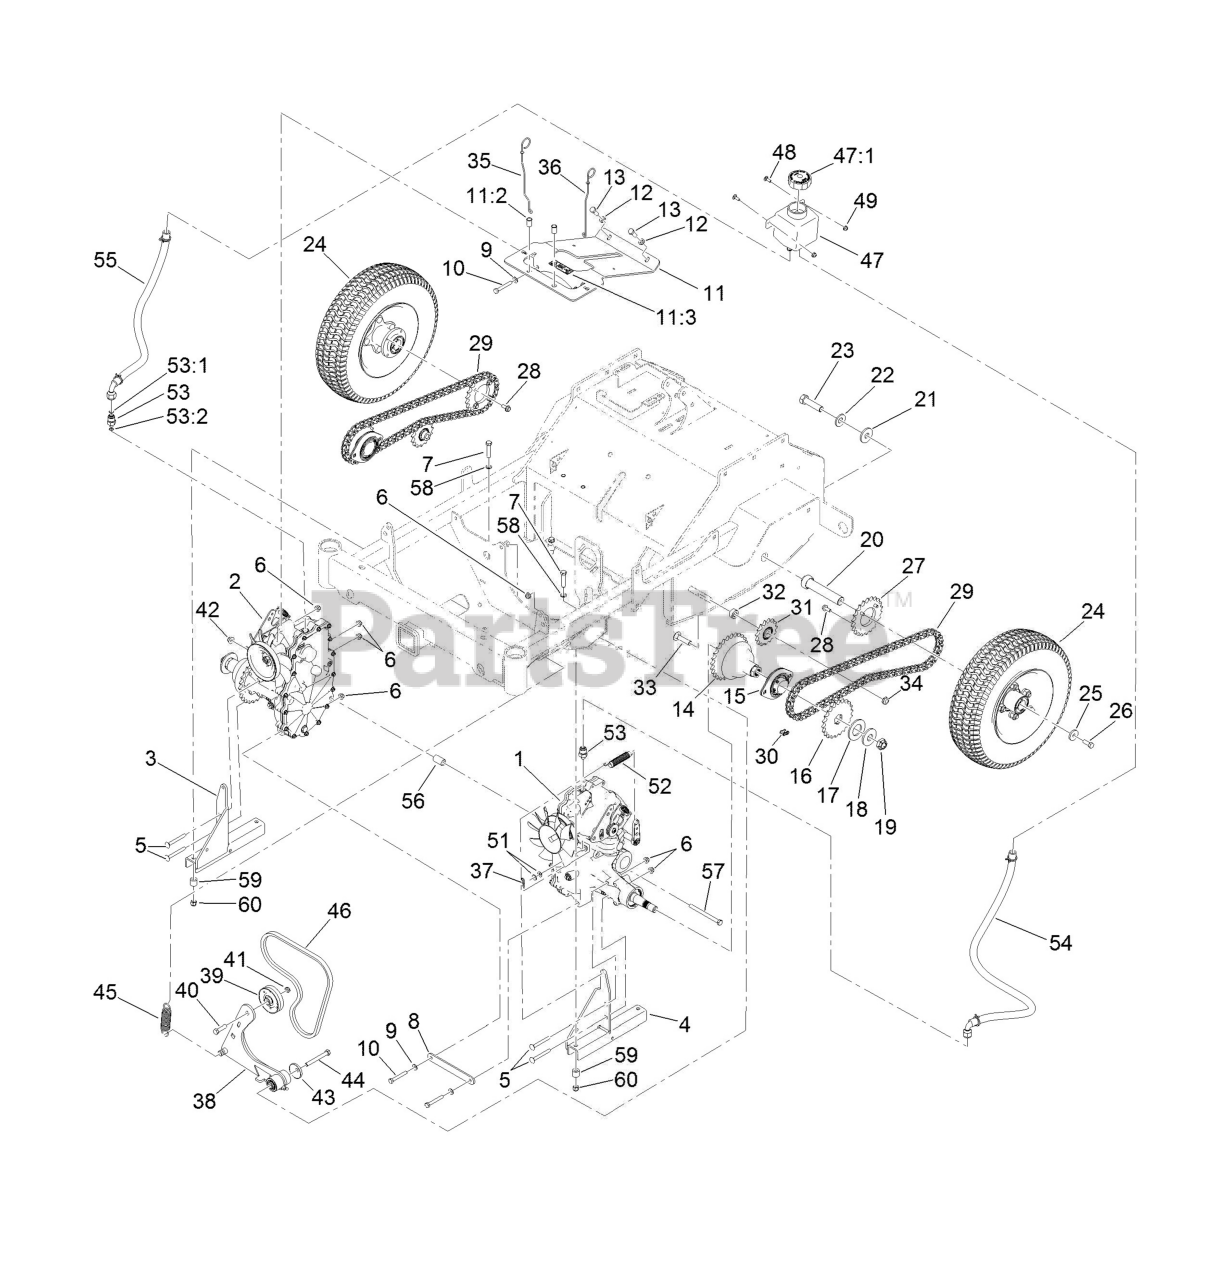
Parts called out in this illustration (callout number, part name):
1	HYDRO-ZT3100, LH
2	HYDRO-ZT3100, RH
3	MOUNT-HYDRO, RH
4	MOUNT-HYDRO, LH
5	SCREW-CARR
6	NUT-HF, NI
7	SCREW-HH
8	Crossmember-Transmission
9	WASHER-SPRING
10	SCREW-HH
11	SUPPORT-COVER
11:2	NUT-CLINCH
11:3	DECAL-DANGER
12	WASHER-LOCK
13	SCREW-HH
14	HUB-BELL
15	BEARING-FLANGED
16	SPROCKET
17	WASHER-SPACER
18	Washer-Belleville
19	NUT-LOCK
20	AXLE-WHEEL, DRIVE
21	WASHER-SPACER
22	Washer-Belleville
23	Screw-HH
24	WHEEL AND TIRE ASM 16X4.5-8, BLACK RIM
25	Washer-Flat
26	SCREW-HH, LOCK
27	SPROCKET
28	SCREW-HHF
29	CHAIN-ROLLER
30	LINK-CONNECTING
31	SPROCKET-IDLER, 15T
33	Screw-CARR
34	NUT-HEX
35	ROD-BYPASS, LH
36	ROD-BYPASS, RH
38	IDLER ARM ASM
39	PULLEY-IDLER
40	SCREW-HH
42	NUT-HF, NI
43	GUARD-TOP
44	SCREW-HH
45	SPRING-EXTENSION
46	BELT-V, COGGED
47	TANK-HYD
47:1	CAP-RESERVOIR, HYD
48	BOLT-CARR
52	SPRING-EXTENSION
53	FITTING-STRAIGHT
53:1	O-RING
54	HOSE ASM
55	HOSE ASM
57	SCREW-HH
58	SPACER-BRAKE, PARKING
60	NUT-LOCK
